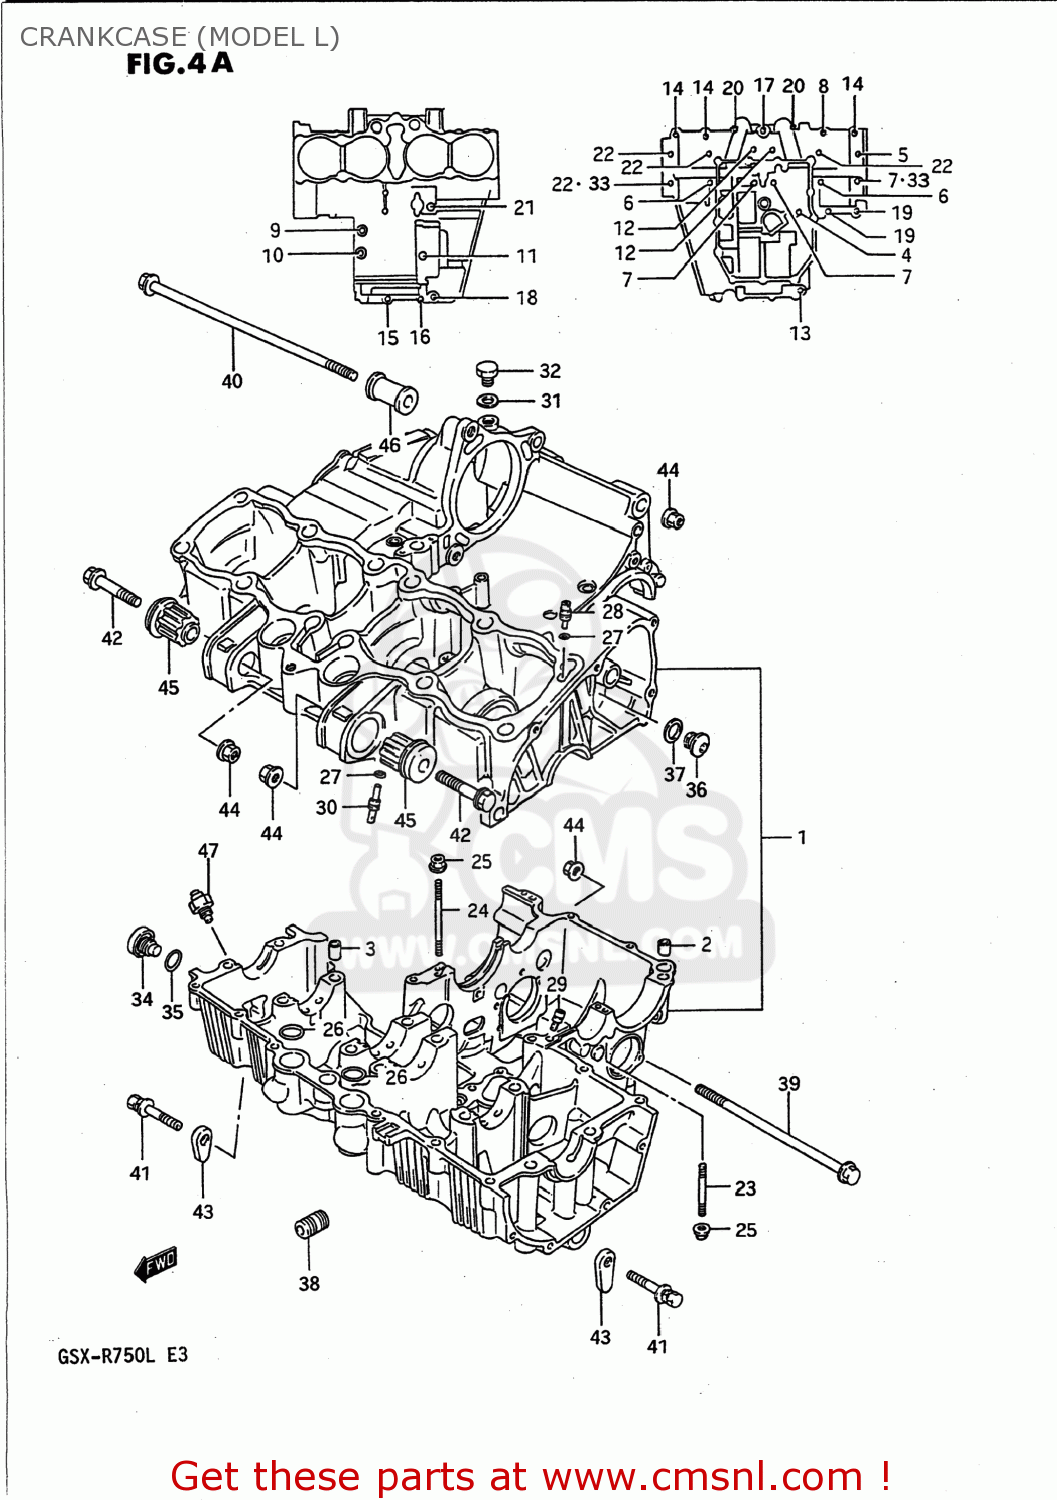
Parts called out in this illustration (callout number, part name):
1	CRANKCASE SET
2	PIN(10.4X13X22)
3	PIN (11X20)(SUS)
4	BOLT(6X105)
5	BOLT
6	BOLT(8X125)
7	BOLT 8X115
8	BOLT 6X35
9	BOLT
10	BOLT
11	BOLT
12	BOLT
13	BOLT 8X60
14	BOLT 6X35
15	BOLT
16	BOLT
17	BOLT 6X50
18	BOLT ,6X60
19	BOLT
20	BOLT
21	BOLT
22	BOLT
23	STUD BOLT
24	STUD BOLT
25	NUT
26	O RING(D:2.5,ID:21)
27	O RING(D:1.2,ID:4)
28	JET,AIR
29	JET
30	JET,OIL GALLERY
31	GASKET(12.1X16.2X3.7) (NAS)
32	PLUG(12X9)
33	GASKET(8.5X17X2.3) (NAS)
34	PLUG
35	O RING(D:2.4,ID:16.8)
36	PLUG
37	GASKET(14X19.2X2) (NAS)
38	UNION,OIL STAND
39	BOLT 10X150
40	BOLT(10X175)
41	BOLT
42	BOLT 10X55
43	NUT
44	NUT
45	BUSH,ENGINE MOUNTING
46	SPACER,ENGINE MOUNT
47	SWITCH ASSEMBLY
